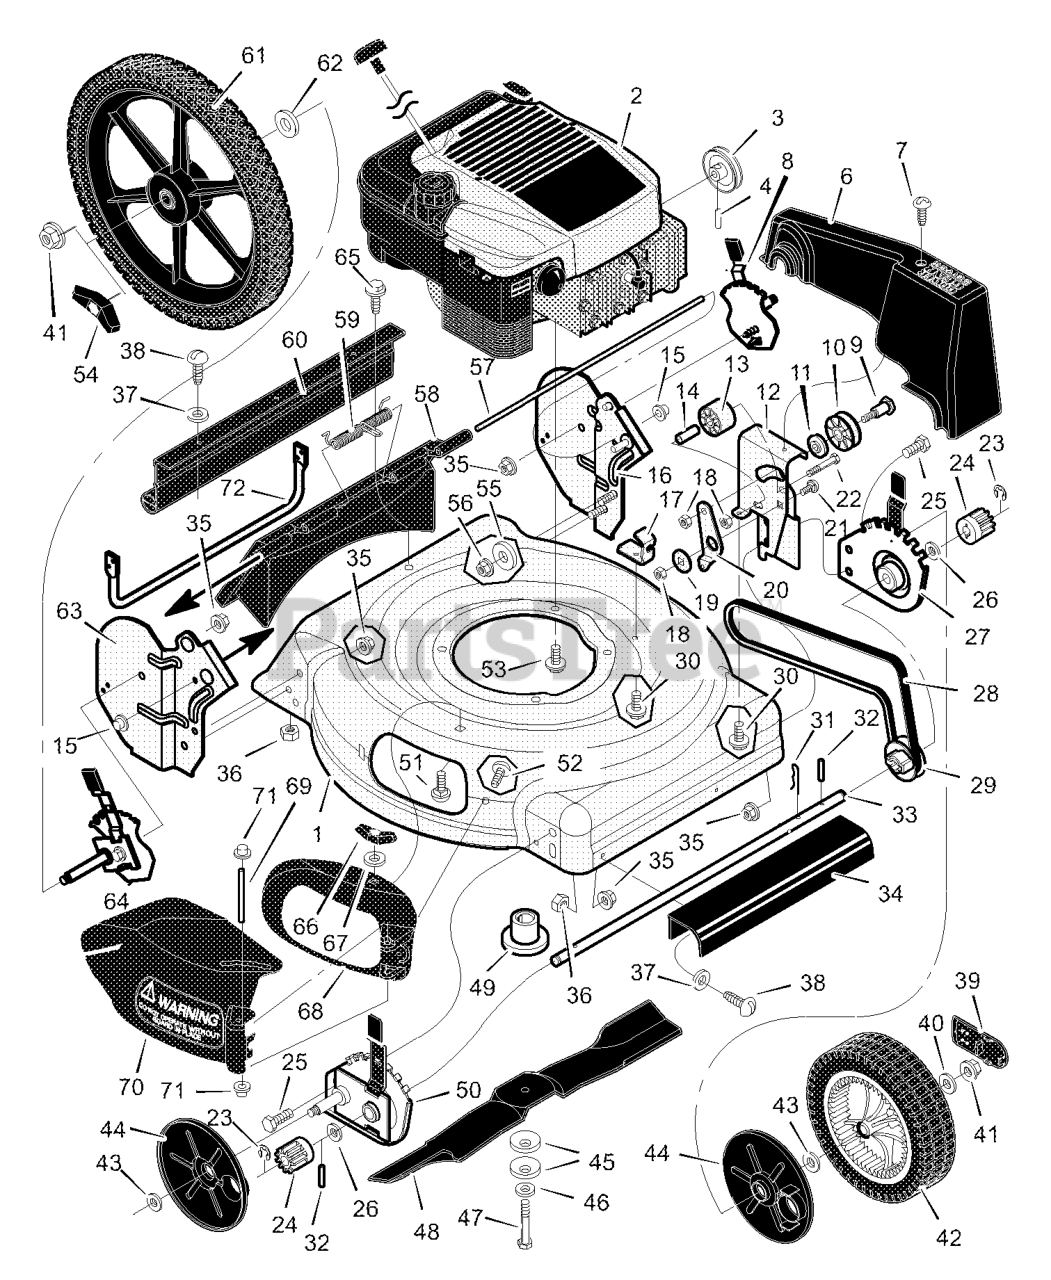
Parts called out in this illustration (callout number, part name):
1	Housing
2	Engine
3	Pulley, Engine
4	Pin, Spring
6	Cover, Belt (Black)
8	Adjuster, Left Rear Height
9	Bolt, Shoulder
12	Bracket, Idler Support
13	Pulley, Idler
14	Bearing
15	Nut, Push
16	Bracket, Left Handle
17	Bracket, Cable
18	Nut, Hex
20	Arm, Idler
21	Bolt, Carriage
22	Bolt, Shoulder
24	Gear, Pinion
25	Bolt
27	Adjuster, Left Frt Height
29	Pulley, Axle
31	Pin, Hair
32	Pin, Spring
34	Cover, Axle (Black)
35	Nut, Flange
36	Nut, Hex
39	Hub Cap
40	Washer
41	Nut, Flange
42	Wheel, Drive
44	Cover, Dust
45	Washer, Belleville
49	Adapter, Blade
50	Adjuster, Right Frt Height
51	Bolt, Carriage
53	Bolt, Engine
54	Knob
55	Washer
56	Nut, Flange
57	Rod, Pivot
58	Door, Rear (Black)
60	Deflector, Rear
61	Wheel, Rear
63	Bracket, Right Handle
64	Adjuster, Right Rear Height
66	Wingnut
67	Retainer, Push
68	Bezel, (Black)
69	Pin, Pivot
70	Deflector, Chute (Black)
71	Push On Cap
